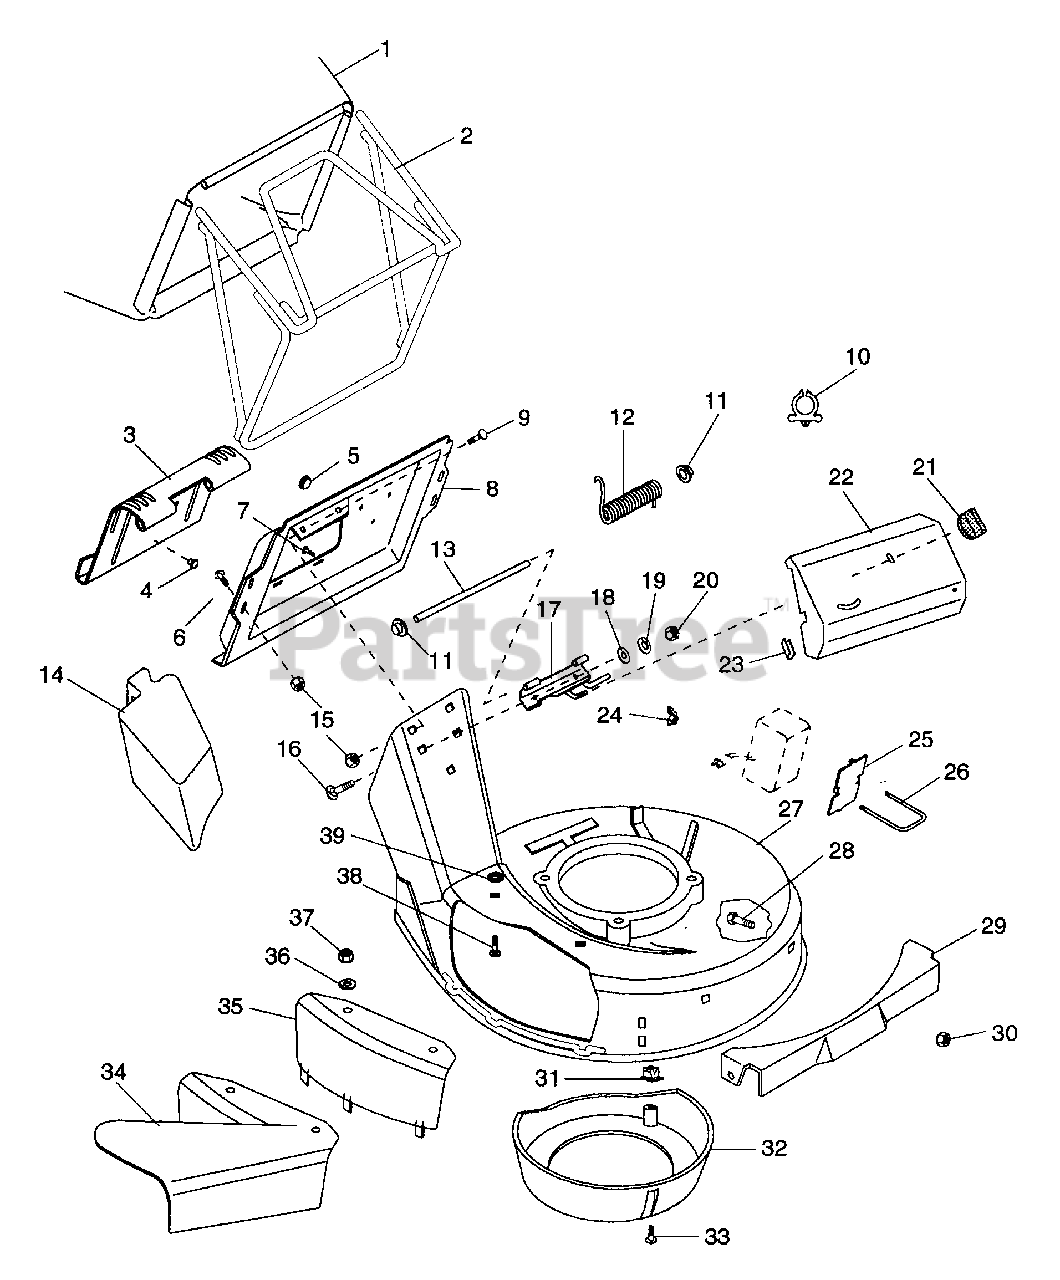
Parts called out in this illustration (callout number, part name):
1	BAG,CONSUMER BLACK 15 OZ/YD2
2	BAGGER FRAME
3	CATCHER PLATE DOOR
4	BUTTON BUMPER
6	SCR-TAP 12-24X.50 HWH PL TR
6	BLT-HEX .25-20X.50 PL GR5
7	SCR-TAP 10-24X.375 TORX PHD
8	CATCHER PLATE
9	@BLT-RHDSSQNK .25-20X.38 G2YZ
10	SNAP-IN CLIP
11	PUSH NUT, .25
12	SG-TORS .120X.68X3.09
13	DOOR PIN
14	MULCH MASTER MULCHER ACCESSORY
15	NUT-LK-FLG .250-20 PL
16	BLT-RDHDSQNK .25-20X.62 PL
17	HINGE BASE
17	HINGE BASE WELDMENT
18	WSHR-FL-STL .380X.875X.179 PL
19	WSHR-LK .250X.077 HVY PL
20	NUT-HEX .250-20 PL
21	WING - NUT
22	DRIVE COVER
22	TRIM BUMPER
24	NUT-WING 8-32
25	HOLD DOWN PLATE
26	U-BOLT
27	MOWER PAN W/DECALS SP/COMM
27	MOWER PAN W/DECALS PUSH
27	MOWER PAN W/DECALS SP
28	BLT-RDHDSQSHNK .31-18X.50 YZ
29	FRONT PANEL
30	NUT-LK .312-18 GR A PL
31	PLASTIC GROMMET
32	CENTER BAFFLE
33	SCR-TAP 10-16X.62 SLPH PL AB
34	SIDE DISCHARGE ASSEMBLY
35	SIDE DISCHARGE COVER
36	WSHR-FL-STL .38X.875X.083 PL
37	NUT-LK-NYL.312-18 PL
38	BLT-RDHDSQNK .31-18X.75 SHT PL
39	NUT-PUSH .312
39	TAPTITE M5-0.8X16MM H-FL-PL
